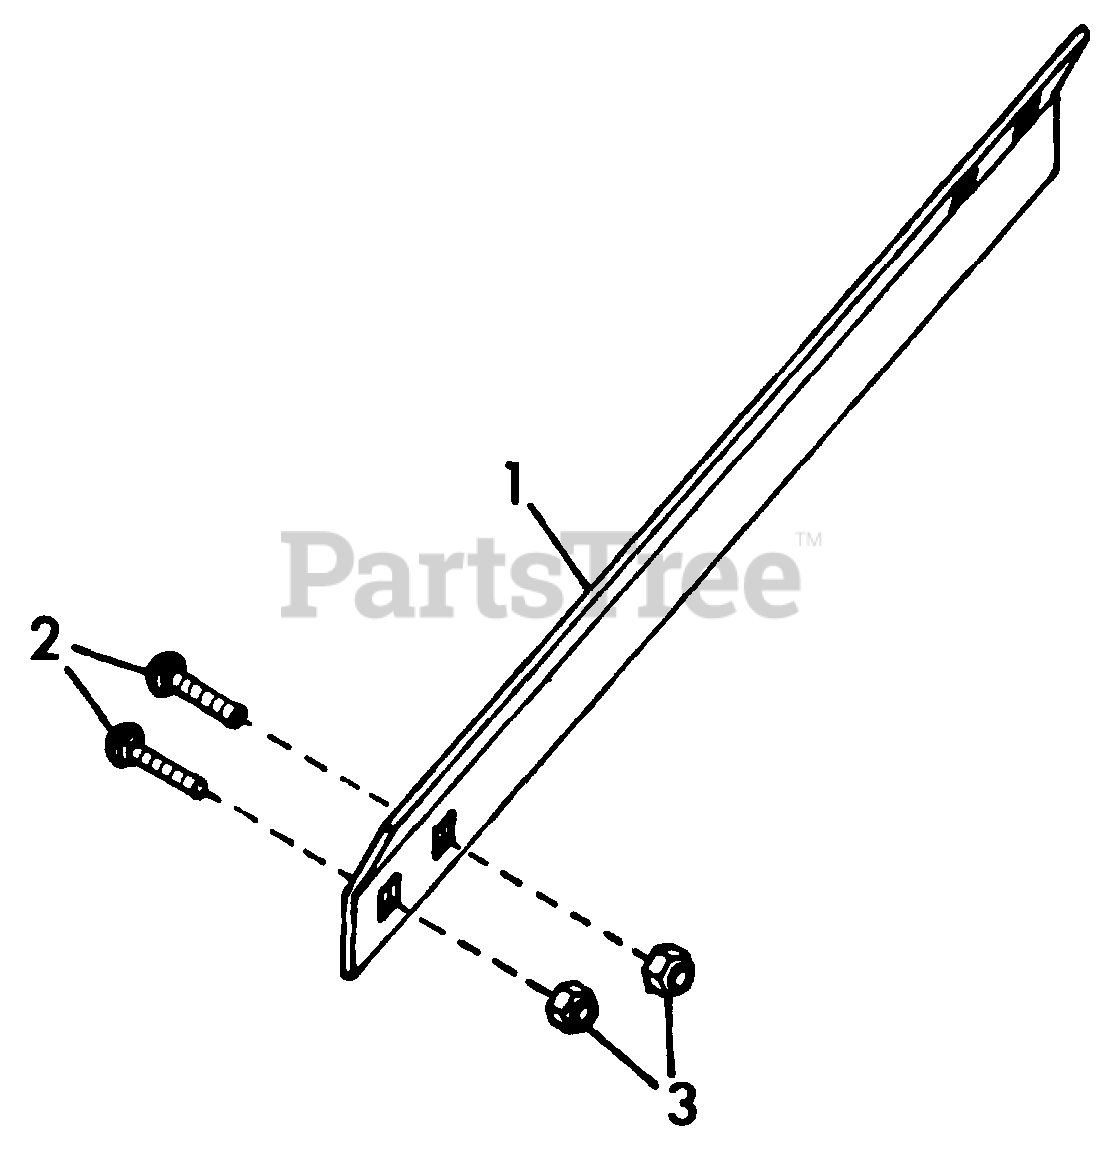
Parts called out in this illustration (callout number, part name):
1	BAR, CUTTER
2	BOLT, 5/16-18 X .625 RD HD SQ NK
3	NUT, LOCK 5/16-18
